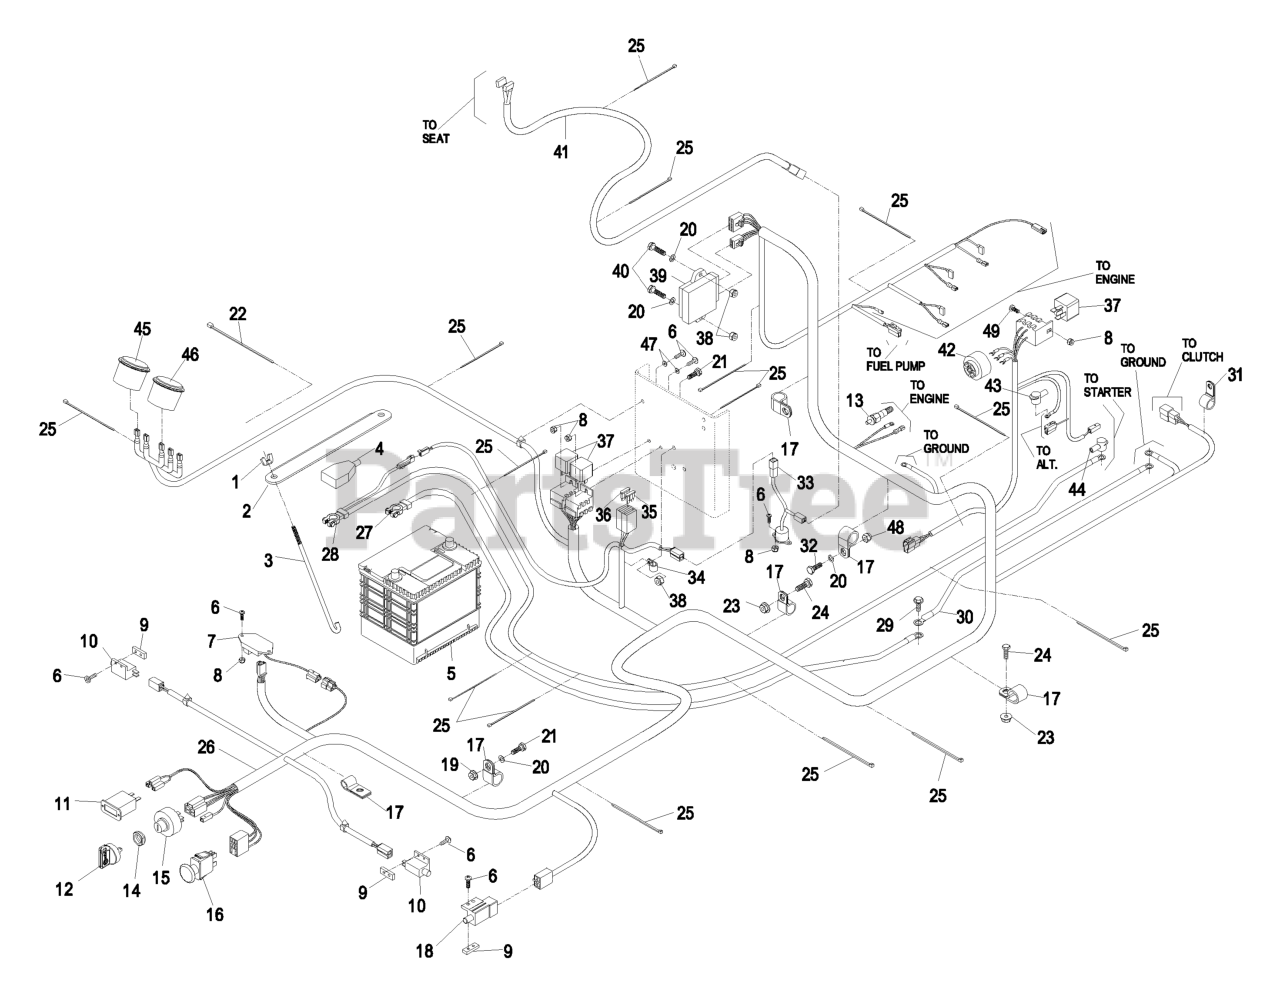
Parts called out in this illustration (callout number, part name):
1	WINGNUT
2	HOLDDOWN-BATTERY
3	BOLT-HOLDDOWN
4	INSULATOR-TERMINAL, BATTE
5	Battery, 12v SAE Post
6	SCREW-PPH
7	MODULE-DELAY, SEAT
8	NUT-LOCK, NI
9	PLATE-TAPPED
10	SWITCH-OPEN, NORMALLY
11	METER-HOUR
12	KEY-IGNITION
13	SENDER-TEMPERATURE
14	NUT-SWITCH, IGNITION
17	CLIP-LOOM
20	WASHER-FLAT
21	SCREW-HH
22	TIE-PLASTIC
24	SCREW-HH
25	TIE-PLASTIC
27	CABLE-BATTERY NEGATIVE
28	CABLE-STARTER
29	Screw-HWH 5/16-18 X 3/4 Tf
30	CABLE-ENGINE NEGATIVE
31	CLIP-LOOM
32	SCREW-HH
34	CLIP-LOOM
35	FUSE-40 AMP
36	FUSE-BLADE TYPE, 20 AMP
38	NUT-LOCK, NI
39	Briggs & Stratton P/N 825273 Module, Ignition Processor
40	SCREW-HH
41	HARNESS-WIRING, SEAT
42	ALARM-TONE, DUAL
43	CAP-INSULATOR, RED
44	INSULATOR-STARTER
45	GAUGE-VOLTMETER
46	GAUGE-TEMPERATURE
47	WASHER-FLAT
48	NUT-LOCK
